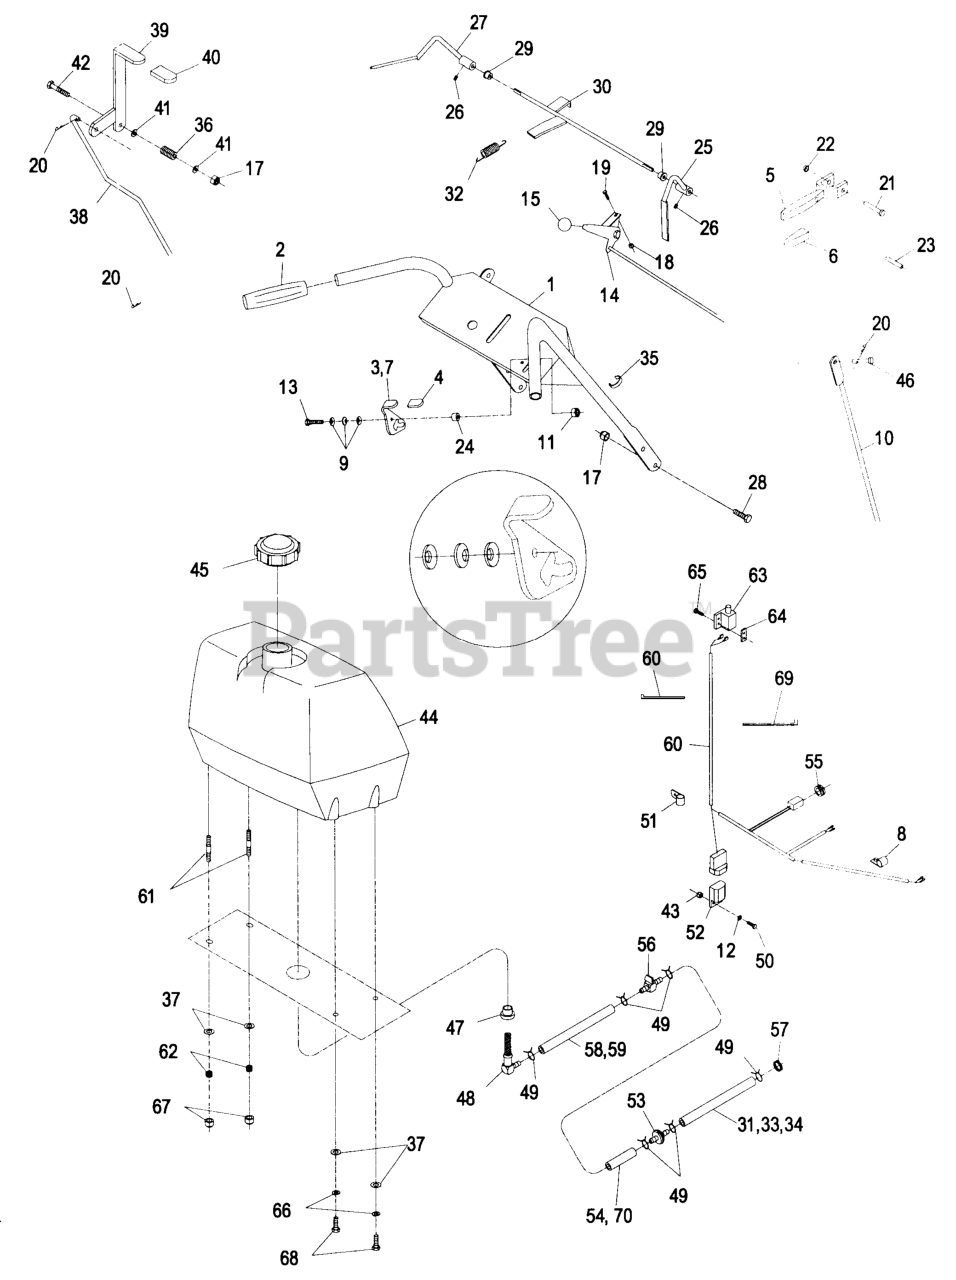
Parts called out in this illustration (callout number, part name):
4	GRIP-LATCH
5	DRIVE LEVER ASM
6	GRIP-LEVER, DRIVE
8	CLIP-LOOM
9	WASHER-SPRING
10	LINKAGE-WHEEL, DRIVE
14	CABLE-CONTROL, THROTTLE
15	KNOB-BALL
16	TIE-CABLE
19	BOLT-CARR
20	PIN-COTTER
21	PIN-LEVER, DRIVE
22	NUT-PUSH
23	PIN-ROLL
25	LEVER-RH
26	SCREW-SET
27	LEVER-LH
29	BUSHING-NYLON
30	WLD,ROD OPC
31	LINE-FUEL
32	SPRING-EXTENSION
33	HOSE-FUEL
34	HOSE-LINE, FUEL
35	CLIP-CABLE
36	SPRING-COMPRESSION
38	LINKAGE-BLADE, UPPER
40	GRIP-LEVER
45	CAP-FUEL
46	PIN-CLEVIS
48	ELBOW-TANK, FUEL
49	CLAMP
51	CLIP-LOOM
52	MODULE-INTERLOCK
54	HOSE-LINE, FUEL
55	GROMMET
56	VALVE-FUEL
57	CLAMP-HOSE
59	HOSE-FUEL
61	STUD
62	SPRING-TANK, FUEL
63	SWITCH-OPEN, NORMALLY
64	PLATE-TAPPED
66	WASHER-LOCK
69	TIE-PLASTIC
70	HOSE-FUEL
